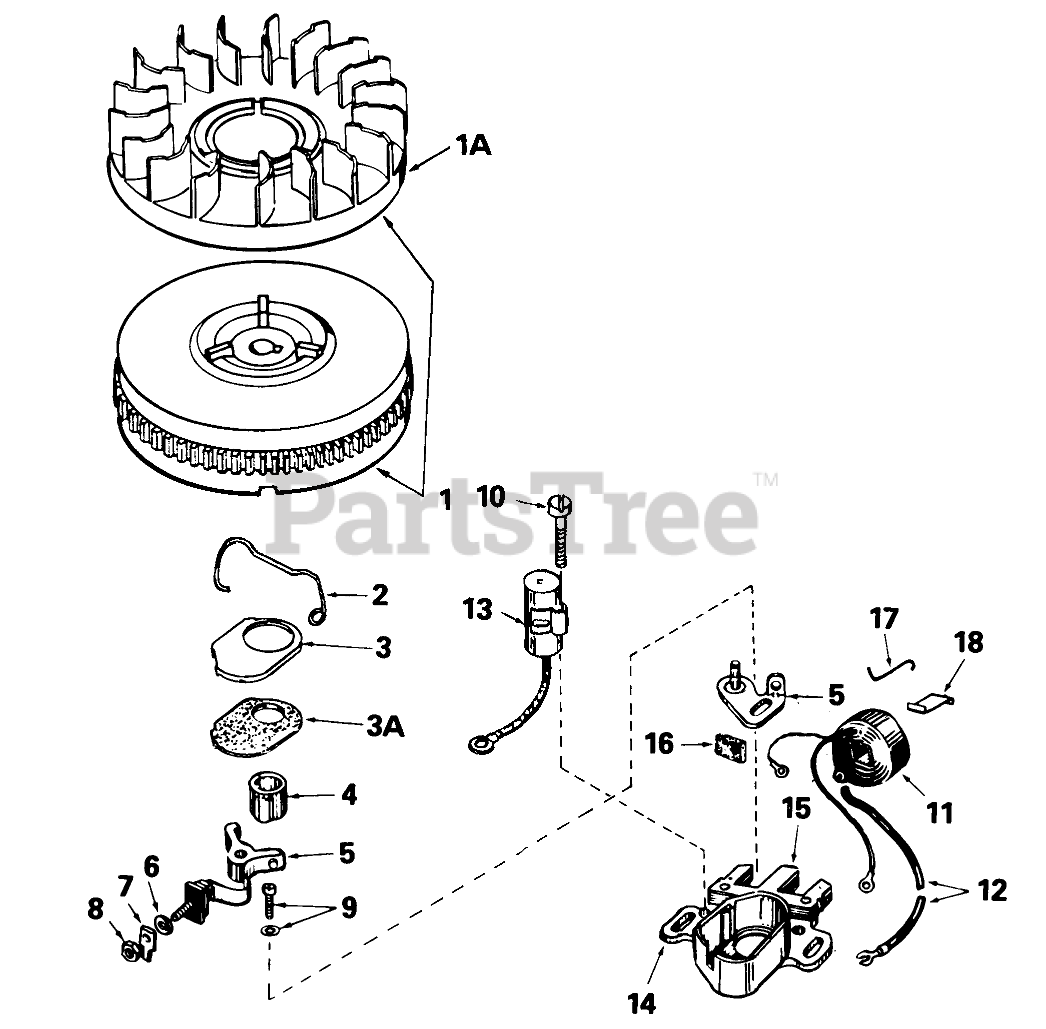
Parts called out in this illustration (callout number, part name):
1	Flywheel (Incl. #1A)
2	Spring Breaker Box
3	Cover-Dust
3A	Gasket-Dust Cover
4	Cam-Breaker
5	Breaker Assy.
7	Terminal, Ground
9	Breaker Screw
10	Condenser Screw
11	Coil Assy. (Incl. #12)
12	Wire, Lead
13	Condenser
14	Core & Plate
15	Stator Assy. (Incl. #2, 3, 3A, 5 thru 14, 16 & 17)
16	Felt,Cam Wiper
17	Clip, Coil
